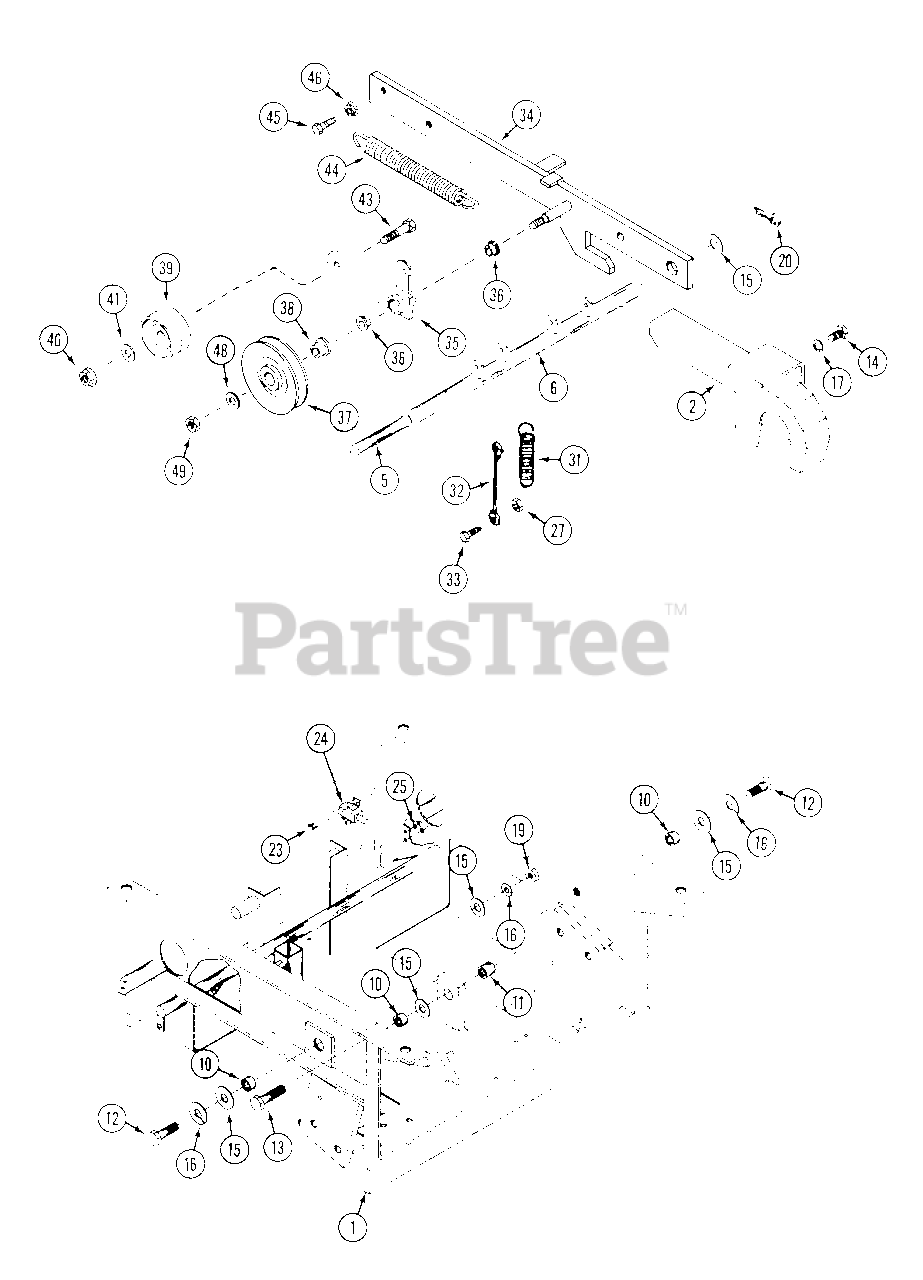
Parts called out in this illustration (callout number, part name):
5	PIN - cross bar
10	BUSHING - deck lift arm (3/8" long)
11	BUSHING - pivot (1/2" long)
12	BOLT - 1/2" - 13 x 1-1/4"
13	BOLT - 1/2" - 13 x 2-1/4"
14	BOLT - 5/16" - 18 x 3/4"
15	WASHER - 1/2"
16	LOCKWASHER - 1/2"
17	LOCKWASHER - 5/16"
19	NUT - 1/2" - 13
20	PIN - cotter 1/8" x 1"
23	SCREW - machine #10 - 32 x 5/8"
24	SWITCH - safety
25	NUT - lock #10 - 32
27	NUT - lock 1/4" - 20
31	SPRING - lift assist
33	BOLT - 1/4" - 20 x 1"
34	ARM - deck L.H.
36	BEARING - flange
37	PULLEY - "V" idler
38	BUSHING - pulley
39	PULLEY
40	NUT - 3/8" - 16 lock, flange
41	WASHER - 3/8"
43	BOLT - 3/8" - 16 x 2"
44	SPRING - extension
45	BOLT - 5/16" - 18 x 1"
46	NUT - 5/16" - 18 flange lock
